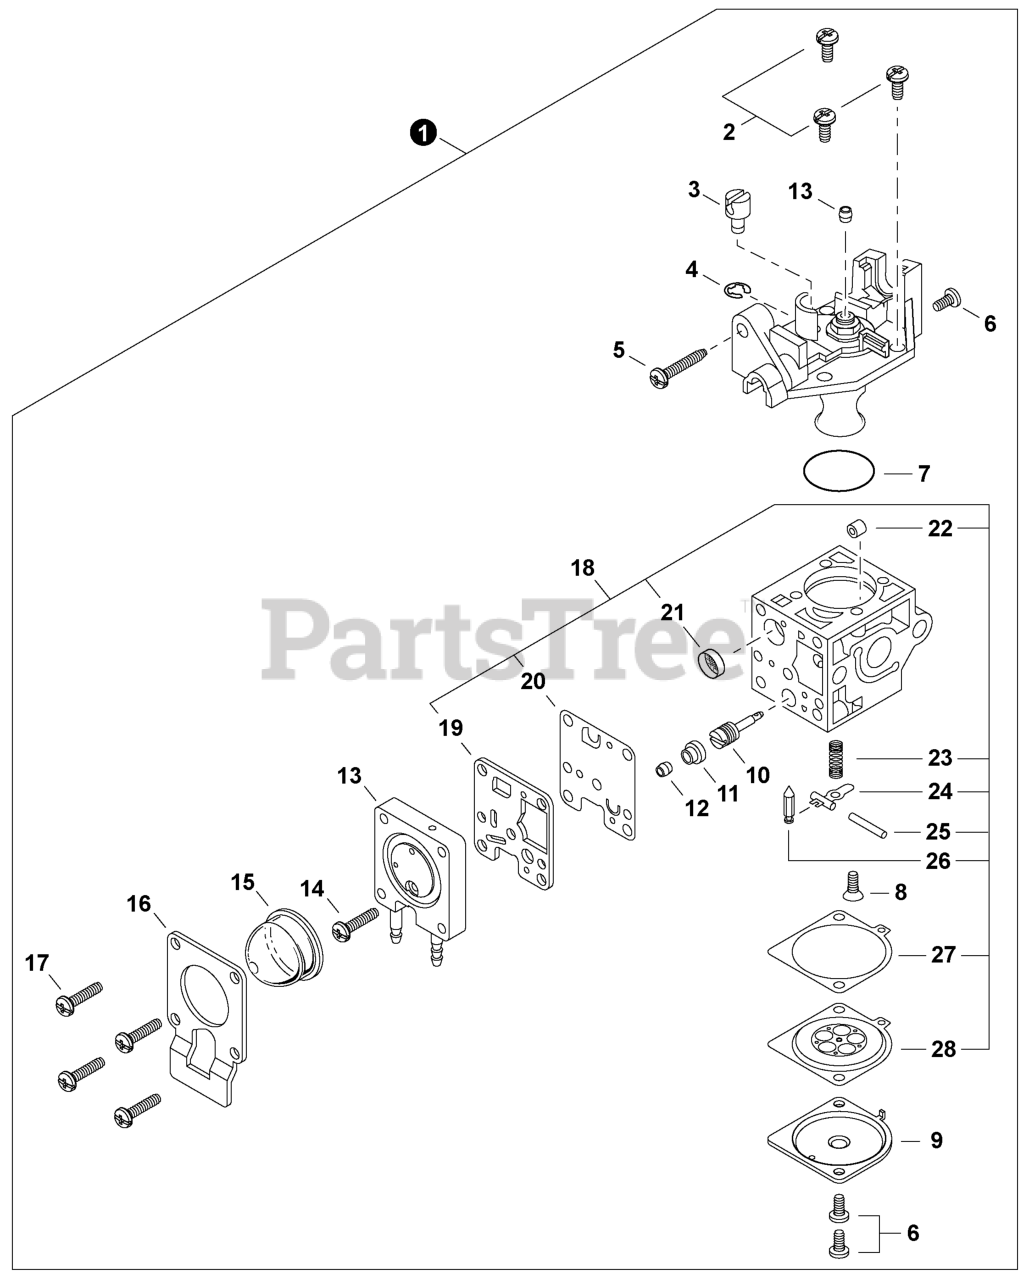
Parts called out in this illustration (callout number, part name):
1	CARBURETOR Z011-0KA
5	SCREW, IDLE ADJUST
9	COVER, METERING DIAPHRAGM
10	NEEDLE, HIGH SPEED
11	CAP, LIMITER
13	BODY ASSY, PURGE
15	BULB, PURGE
16	RETAINER, PURGE BULB
18	REPAIR KIT, CARBURETOR
19	GASKET, PUMP
20	DIAPHRAGM, PUMP
21	SCREEN, FUEL INLET
22	GUIDE, ROLLER
23	SPRING, METERING LEVER
24	LEVER, METERING
25	PIN, METERING LEVER
26	VALVE, INLET NEEDLE
27	GASKET, METERING DIAPHRAGM
28	DIAPHRAGM, METERING
